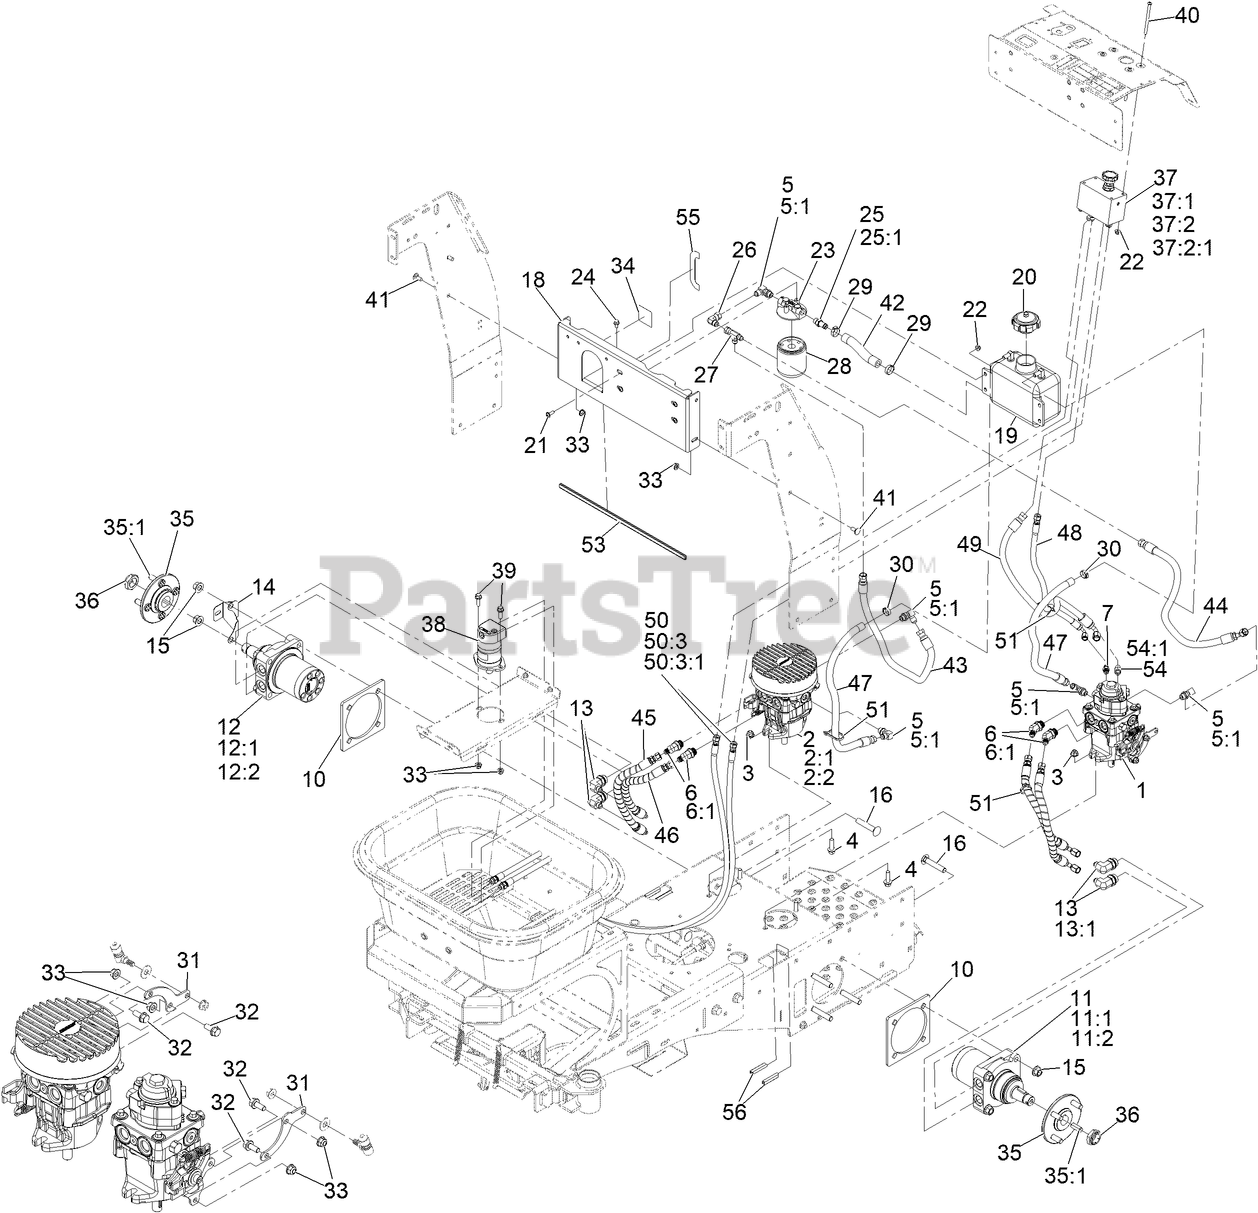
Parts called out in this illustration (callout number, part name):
1	PUMP-HYDRO, PG WITH AUX
2	PUMP-HYDRO, PG
2:1	HYDRO PUMP FAN
2:2	GUARD-PUMP
3	Nut-Hex Flange
4	SCREW-HHF
5	FITTING-ELBOW, 90 DEG
5:1	O-RING
6	FITTING
6:1	O-RING
7	FITTING-STRAIGHT
10	BACKPLATE, WHEEL, JR36
11	MOTOR-WHEEL,LT
11:1	KEY-WOODRUFF
11:2	KIT-SEAL, TJ MOTOR
12	MOTOR-WHEEL,RT
12:1	KEY-WOODRUFF
12:2	KIT-SEAL, TJ MOTOR
13	FITTING-ELBOW, 90 DEG
13:1	O-RING
14	BRACKET-HOPPER, SPEEDOMET
15	Nut-Lock 1/2-13
16	SCREW-CARR
18	MOUNT, HYDRAULIC FILTER,
19	2 QT FLAMBEAU HYDRO TANK
20	Cap-Vented
21	Screw-Hsbhf
22	Nut-Hex Flange
23	HEAD-FILTER
24	SCREW-HHF
25	ADAPTER-STRAIGHT
25:1	O-RING
26	ELBOW-SWIVEL, 90 DEG
27	FITTING-HYD, TEE
28	FILTER-25 MICRON, BI-DIRECTIONAL
29	CLAMP-OETIKER, 167
30	CLAMP-OETIKER, 167
31	EXTENSION, HYDRO-PUMP, JR
32	SCREW-HHF
33	Nut-Hex Flange
34	DECAL-OIL
35	HUB-WHEEL
35:1	STUD-1/2-20 X 1.55
36	LOCKNUT
37	Manifold-Flow Control, Hopper
37:2	FITTING-ELBOW, 45 DEG
37:2:1	O-RING
38	MOTOR-HYDRAULIC, SPREADER
39	SCREW-HHF
40	Screw-HSBH
41	SCREW-CARR
42	HOSE-HYDRAULIC
43	HOSE ASM, HYD LP
44	HOSE ASM, HYD LP
45	HOSE ASM-HYD HP
46	HOSE ASM-HYD HP
47	HOSE ASM, HYD LP
48	Hose ASM-HYD HP
49	HOSE ASM, HYD LP
50	HOSE ASM-HYD HP
50:3	Fitting-Straight, Rigid
50:3:1	O-RING
51	TIE-CABLE
53	STRIP-TRIM, 17.88""
54	Adapter-Straight
54:1	O-RING
55	DECAL-HYDRO LEVEL
56	STRIP-TRIM, 2.0""
